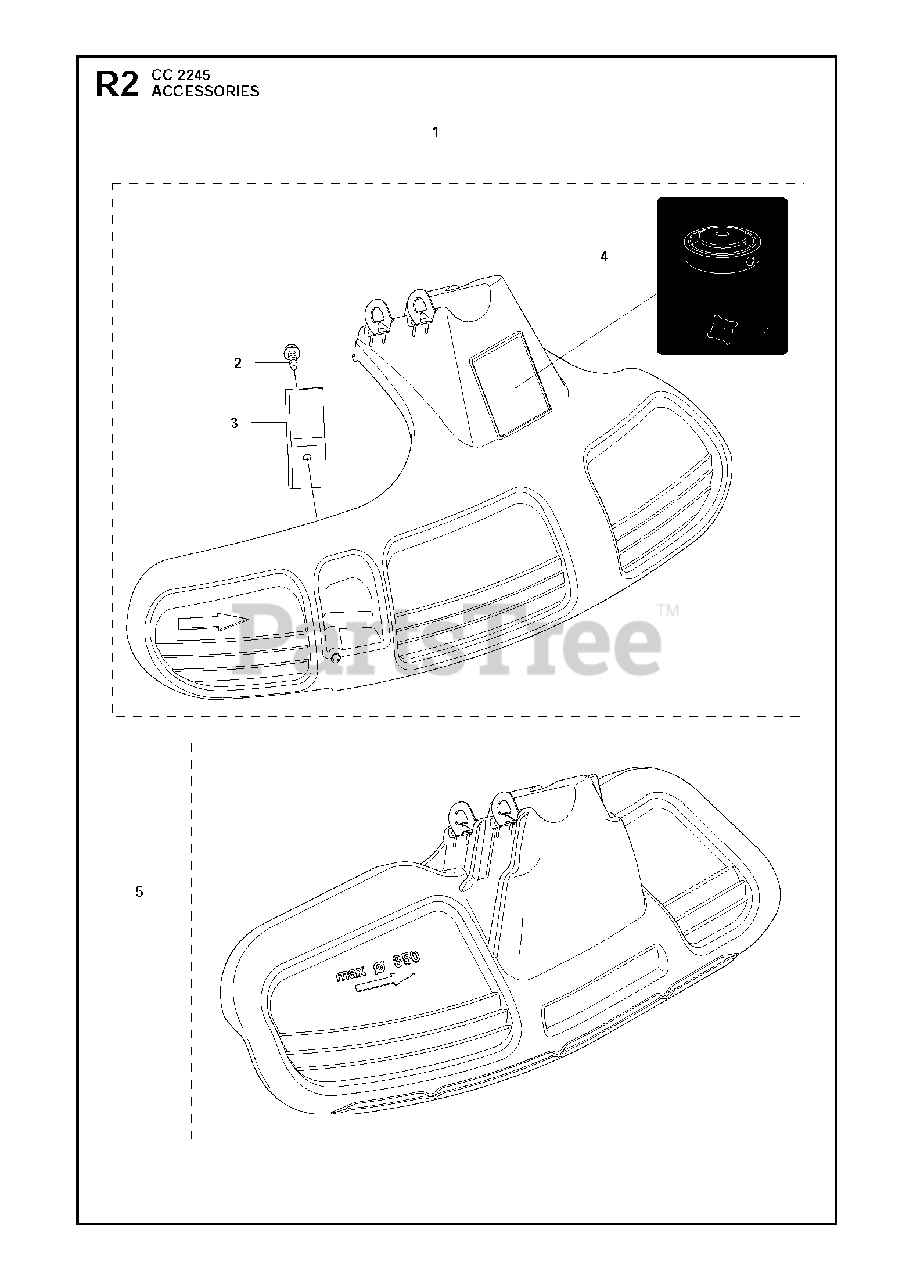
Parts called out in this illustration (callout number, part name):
1	TRIMMER GUARD W/ CUTTER
2	SCREW
3	LINE CUTTER
4	DECAL
